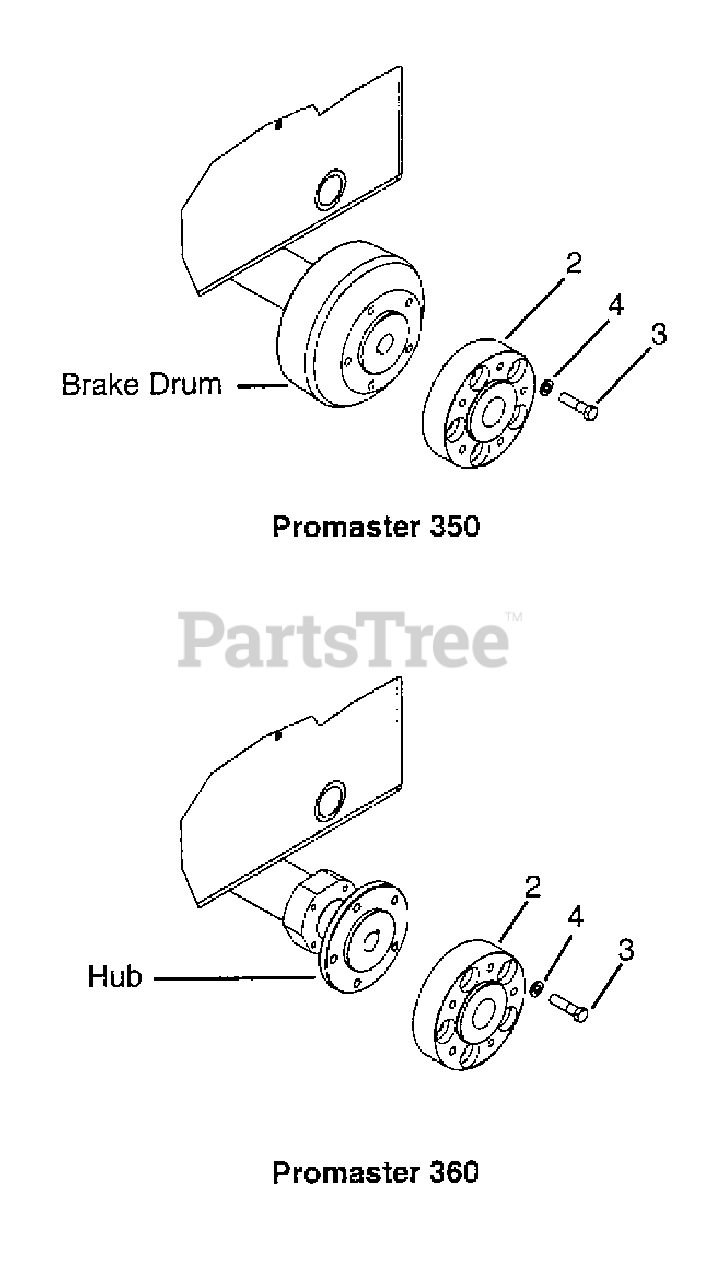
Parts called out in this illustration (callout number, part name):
1	Tire Chains (set of 2)
2	Spacer-Wheel
3	Bolt-Hex .44-20 x 1.75 Grade 5
4	Washer-Locking .44 x .109
